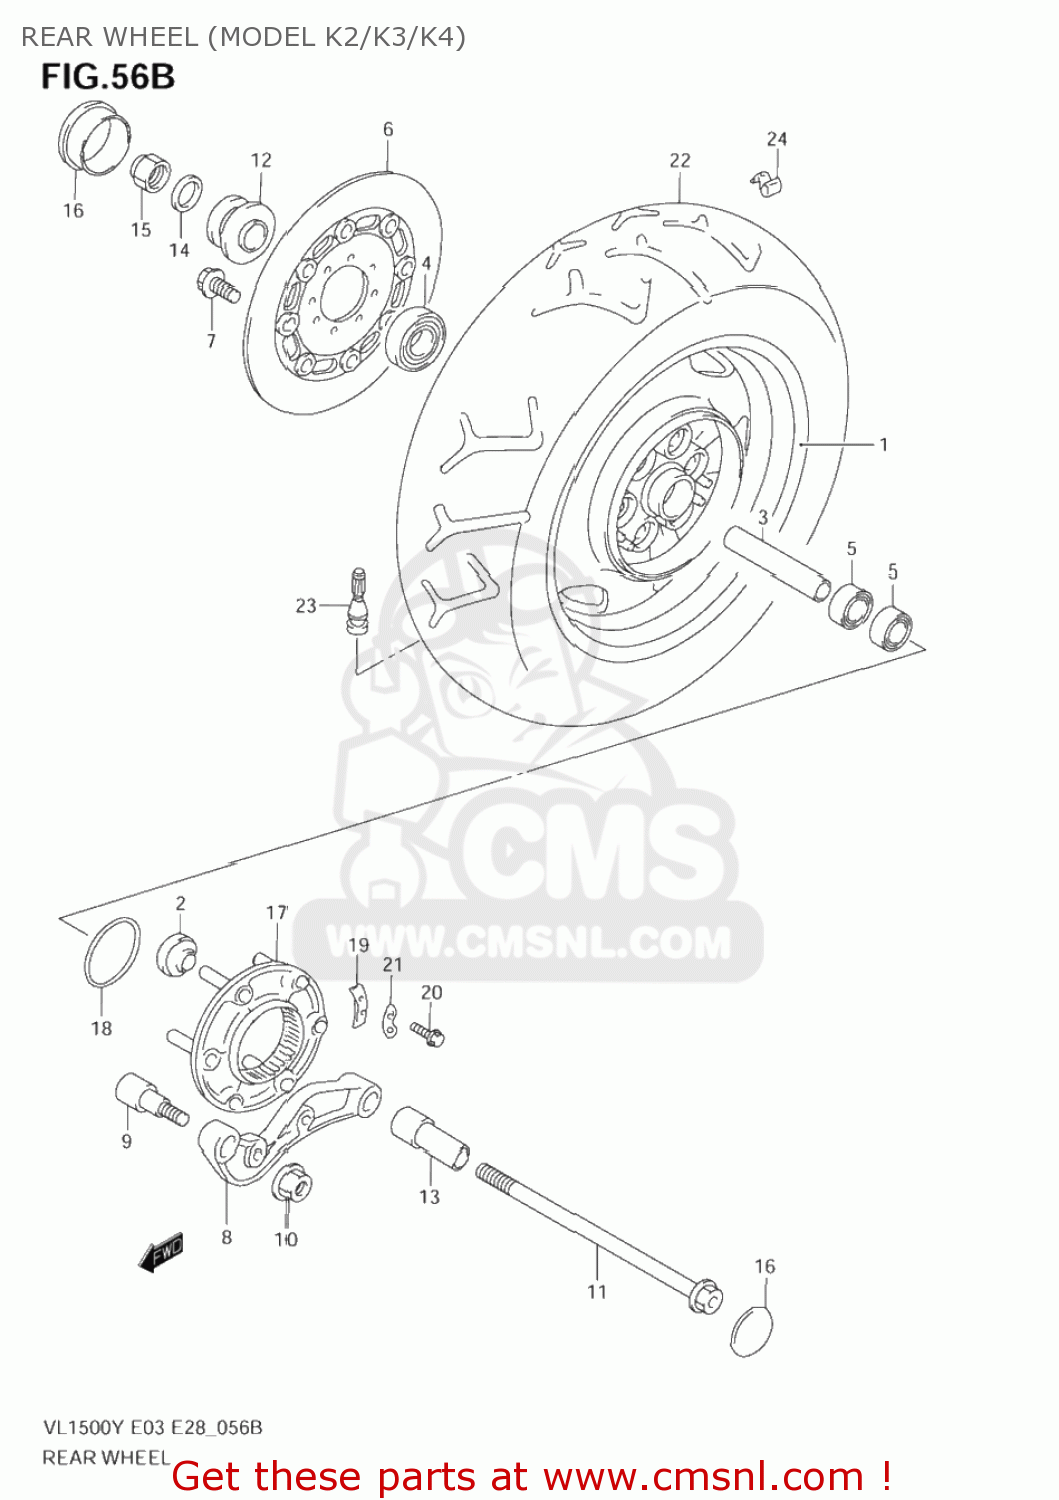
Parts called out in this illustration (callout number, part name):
1	WHEEL SET,RR(MT5.00X15)
2	BUSH
3	SPACER(20.8X27.2X124)
4	BEARING WHEEL REAR(20X47X14)
5	BEARING(20X47X14)
6	DISC,REAR BRAK
7	BOLT(8X33)
8	BRACKET,RR CALIPER
9	PIN,CALIPER BRACKET
10	NUT
11	AXLE,RR
12	SPACER,RR AXLE,R
13	SPACER,RR AXLE,L
14	WASHER
15	NUT
16	CAP,RR AXLE,L
17	JOINT ASSY,RR HUB DRIVEN
18	O RING(D:2.1,ID:65)
19	WASHER,THRUST(T:1.6)
20	BOLT(6X16)
21	WASHER
22	TIRE,RR(180/70-15M/C 76H)
23	VALVE ASSY,WHEEL RIM(TR412)
24	WEIGHT,BAL. 30
